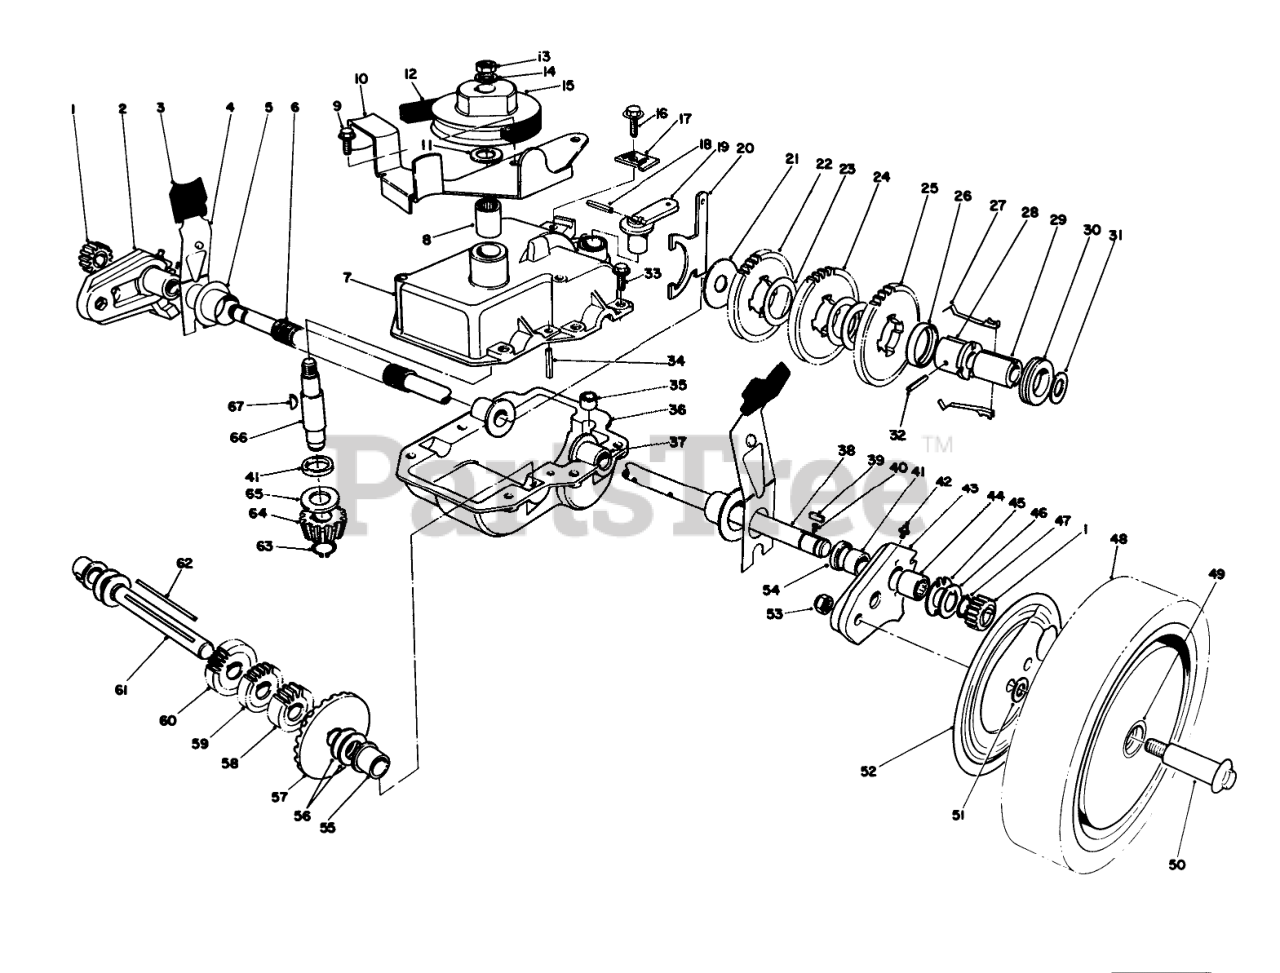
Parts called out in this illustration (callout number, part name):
1	GEAR-PINION
2	Pivot Arm Assembly-R.H. (Incl. Ref. #41, 42, 44 & 54)
3	KNOB-ARM
4	SPRING ARM ASM SP
5	CAP-END
6	CONDUIT-CONVOLUTED, SPLIT
7	Case-Upper
8	BEARING
9	SCREW
10	BELT GUIDE BRKTB
11	WASHER-THRUST
12	V-BELT
13	NUT-HEX
14	WASHER-FLAT
15	PULLEY
16	SCREW-HWHTF
17	Cable Clamp
18	PIN-COIL
19	LEVER-SHIFT
20	Shift Yoke
21	WASHER
22	GEAR-38T
23	WASHER
24	GEAR-42T
26	RETAINER-KEY
27	KEY-SHIFT
28	SLEEVE-GEAR
29	SLEEVE
30	COLLAR-SHIFT
31	WASHER-PLAIN
32	PIN-SPRING
33	SCREW-HWHTF
34	ROLL PIN 3/16 X 1 IN
35	BUSHING-YOKE
36	LOWER GEAR CASE CAST
37	Bushing-Output Shaft
38	Output Shaft
39	KEY RECTANGULAR
40	SPRING-COMPRESSION
41	BUSHING
42	FITTING-GREASE
43	Pivot Arm Assembly-L.H. (Incl. Ref. #41, 42, 44 & 54)
44	Needle Bearing
45	INNER THRUST WASHER
46	WASHER-THRUST, OUTER
47	RING-RETAINING
48	Wheel, Tire & Gear Assembly (Incl. Ref. #49)
49	BUSHING
50	WHEEL BOLT
51	WASHER
52	WHEEL COVER
53	Nut
55	BUSHING
56	WASHER-THRUST
57	BEVEL GEAR
58	GEAR-12T
59	GEAR-14T
60	GEAR-18T
61	INTERMEDIATE SHAFT
63	RING-RETAINING
64	PINION-BEVEL
65	WASHER-THRUST
66	INPUT SHAFT
67	KEY-WOODRUFF
